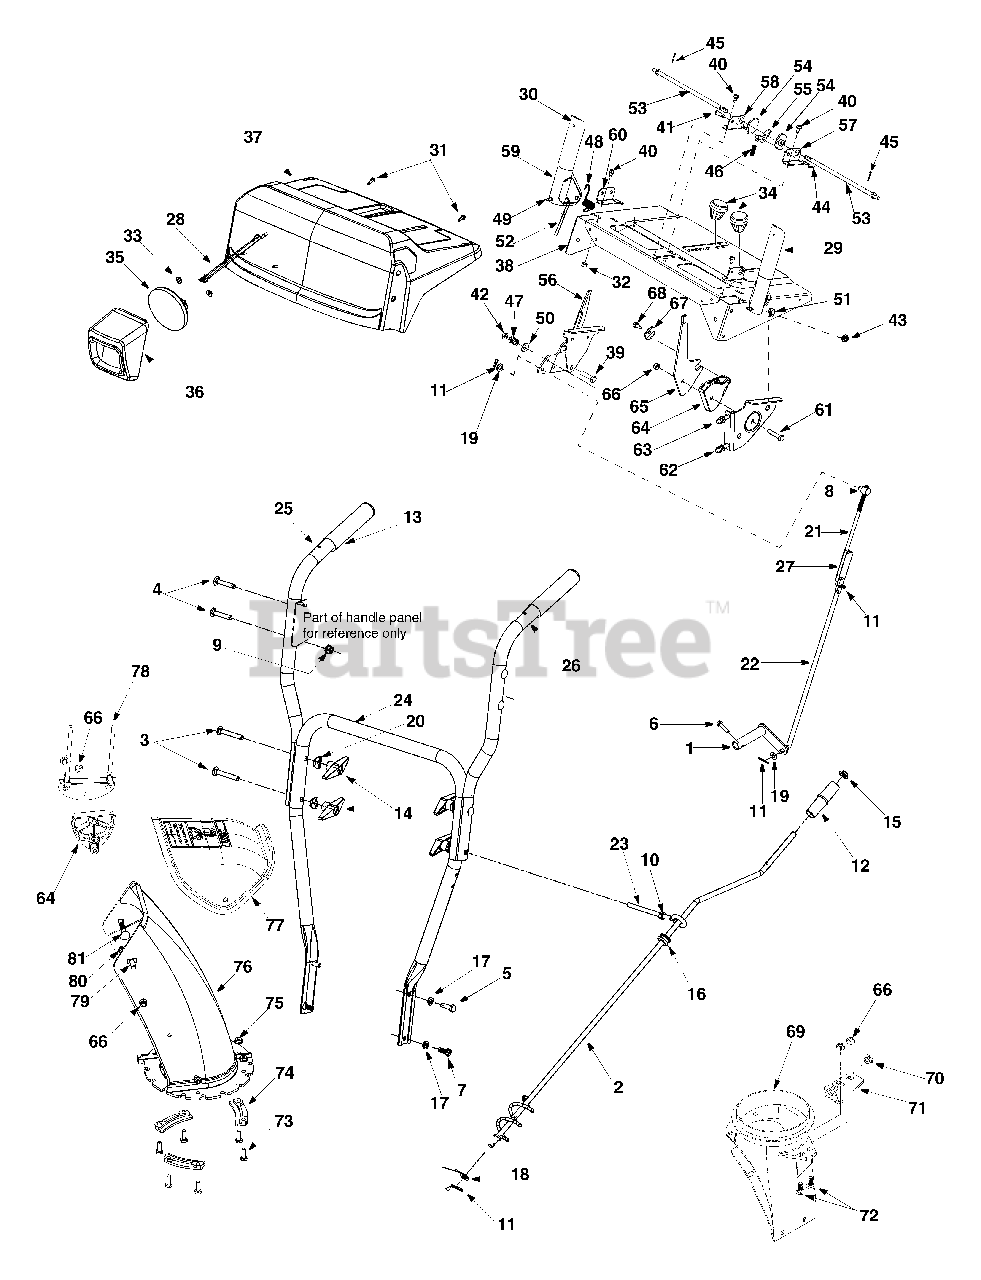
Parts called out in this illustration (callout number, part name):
2	Chute Directional Control
3	Carriage Screw 5/16-18 x 2.25
4	Carriage Bolt 5/16-18 x 1.75
5	Hex Bolt 5/16-18 x 1.0
6	Tt Screw 1/4-20 x 1.0
7	Hex Bolt 5/16-18 x 0.75
8	Ferrule
9	Flange Lock Nut
10	Hex Nut 5/16-18
11	Hairpin Clip
12	Knob: Chute Directional Control
14	Handle Knob Assembly
15	Push Cap
16	Rubber Grommet
17	Lock Washer
18	Flat Washer
19	Flat Washer
20	Saddle Washer
21	Upper Shift Rod
22	Lower Shift Rod
23	Eye Bolt
28	Harness: Light
29	Handle Engagement Assembly LH
30	Handle Engagement Assembly RH
31	B Screw #10-16 x 0.625
32	Hex Sems Nut 1/4-20
33	Hex Nut
34	Shift Knob
35	Headlight
36	Headlight Bezel
37	Handle Panel
39	Hex Bolt 3/8-24 x 1.5
40	TT Screw 1/4-20 x 0.5
41	Clevis Pin
42	Jam Lock Nut 3/8-24
43	Flange Lock Nut
44	Cotter Pin
45	Cotter Pin
46	Compression Spring
47	Compression Spring
48	Torsion Spring
49	Rubber Bumper
50	Bell Washer
51	Flat Washer
52	Z Fitting: Clutch Cable
53	Cam Rod
54	Cam: Handle Lock
55	Pawl: Handle Lock
61	Hex Bolt 5/16-18 x 1.5
62	Chute Deflector Cable w/Clip
63	Chute Deflector Control Cable
64	Chute Cable Guide
66	Flange Lock Nut 5/16-18
67	Special Washer
68	Hi-Lo Screw 1/4-15 x 0.75
69	Chute Adapter
70	Plastic Bushing
72	Carriage Bolt 5/16-18 x 0.75
73	Hex Bolt 1/4-20 x 1.0
74	Flange Keeper
75	Flange Lock Nut 1/4-20
76	Lower Chute
77	Upper Chute
79	Carriage Bolt 5/16-18 x 1.0
80	Hi-Lo Screw 1/4-15 x 0.75
81	Carriage bolt 5/16-18 x 1.5
